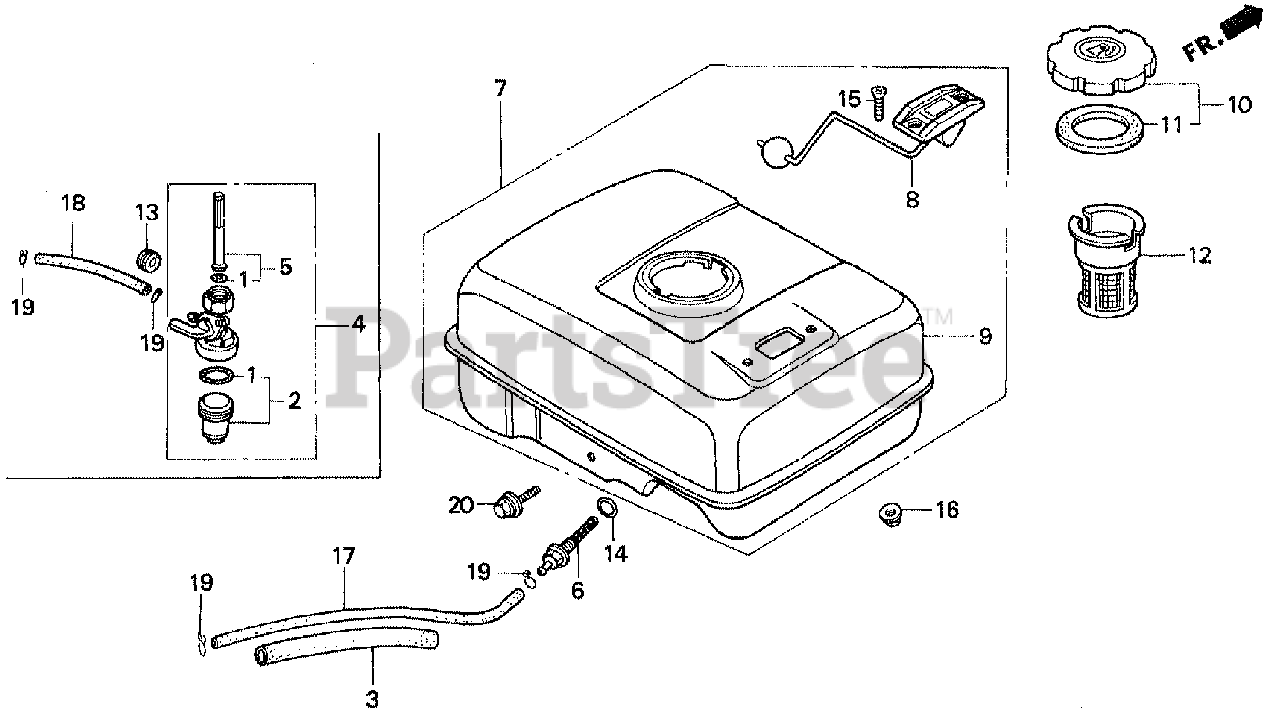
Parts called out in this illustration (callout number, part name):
3	RUBBER, SUPPORTER (107MM)
6	JOINT, FUEL TANK
9	TANK, FUEL *NH31* (MCKINLEY WHITE)
10	CAP, FUEL FILLER
11	GASKET, FUEL FILLER CAP
14	O-RING (13.5X1.5) (ARAI)
16	NUT, FLANGE (6MM)
17	BULK HOSE, FUEL (4.5X3000) (4.5X140)
19	CLIP, TUBE (B8)
20	BOLT, FLANGE (6X29)
20	BOLT, FLANGE (6X25)
